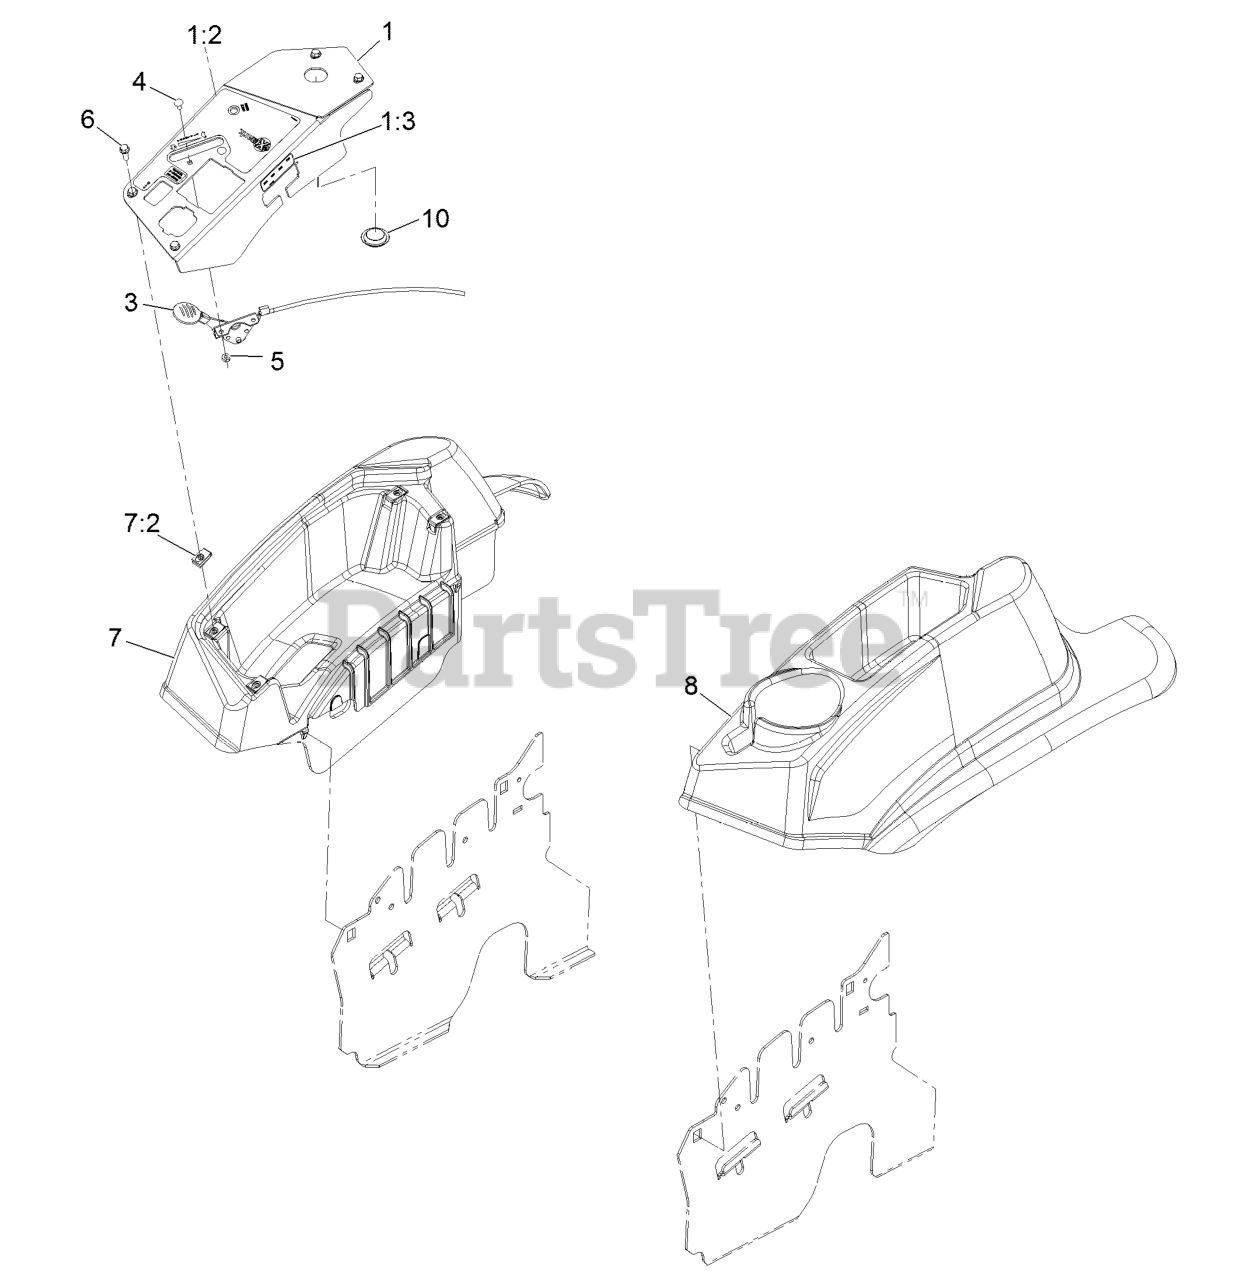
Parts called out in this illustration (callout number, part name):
1	ASM,CONTROL PANEL W/DECAL
1:2	DECAL,CONTROL PANEL EFI
1:3	DECAL-FUSE
3	ASM,THROTTLE CABLE
4	BOLT-CARR
5	NUT-LOCK, NI
6	SCREW-HWH
7	CONSOLE,RH AS ASM
7:2	Nut-Retainer-Panel 1/4-20
8	CONSOLE, LH AS
10	PLUG-PLASTIC
